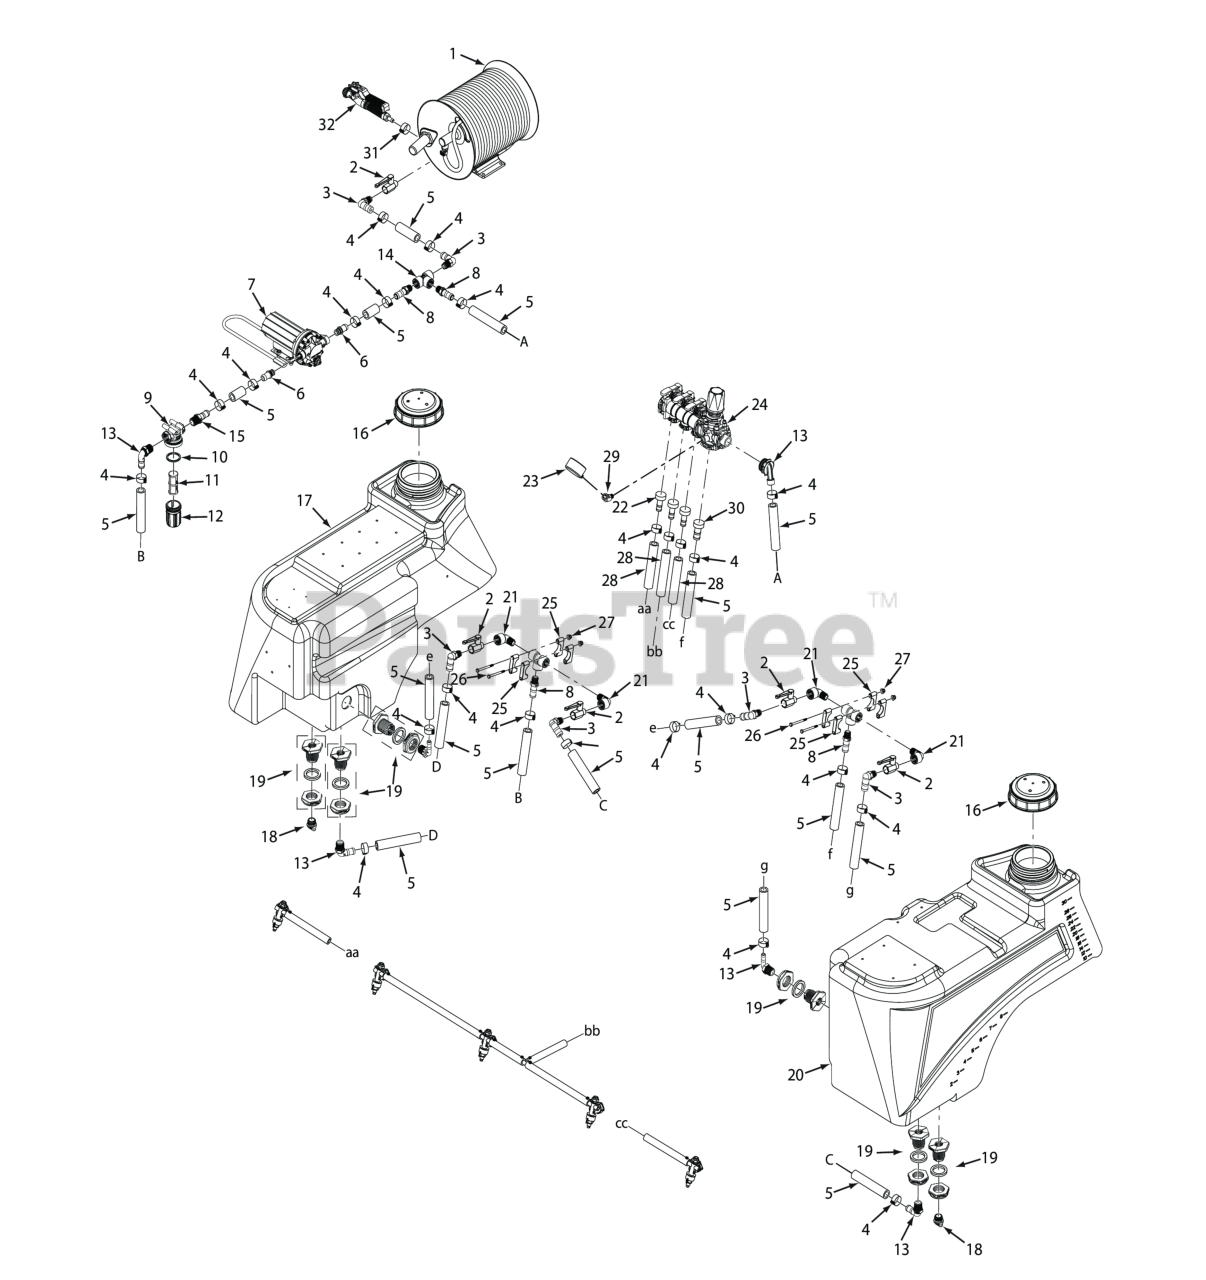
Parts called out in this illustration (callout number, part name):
1	Hose Reel Assy
2	Valve, Ball 1/2" NPT
3	Fitting, 90 Deg.1/2 - 14 NPT X 3/4" Hose
4	CLAMP, WORM DRIVE
5	Hose, 3/4" EPDM ( Order by the inch)
6	Fitting, 3/4" O-ring
7	Pump, 12V Electric
8	Hose Barb, 1/2" NPT X 3/4" Hose
9	Strainer Head
10	Gasket
11	Screen
13	Fitting, 90 Deg. 3/4 - 14 NPT x 3/4" Hose
14	Tee Fitting, 1/2 NPT
15	Hose Barb, 3/4 NPT x 3/4" Hose
16	Cap, Sprayer
17	Tank Assy, RH
18	Drain Plug, 3/4"
19	Fitting, 3/4" NPT
20	Tank Assy, LH
21	Fitting, Street Elbow 90 Deg. 1/2"
22	Fitting, Valve
23	Pressure Gauge
24	Valve Assy (Incl.
25	Mounting Bracket, Valve Assy
26	Bolt, 1/4 - 20 x 2.75 - Stainless Steel
27	Locknut, 1/4 - 20 Flg. Elastic Stop - Stainless Steel
28	Hose, 1/2" EPDM (order by the inch)
29	Fitting, 45 Degree 1/4 NPT
30	Fitting, Valve
31	Clamp, .69" Max. / .25" Min. Dia.
32	Sprayer Gun
